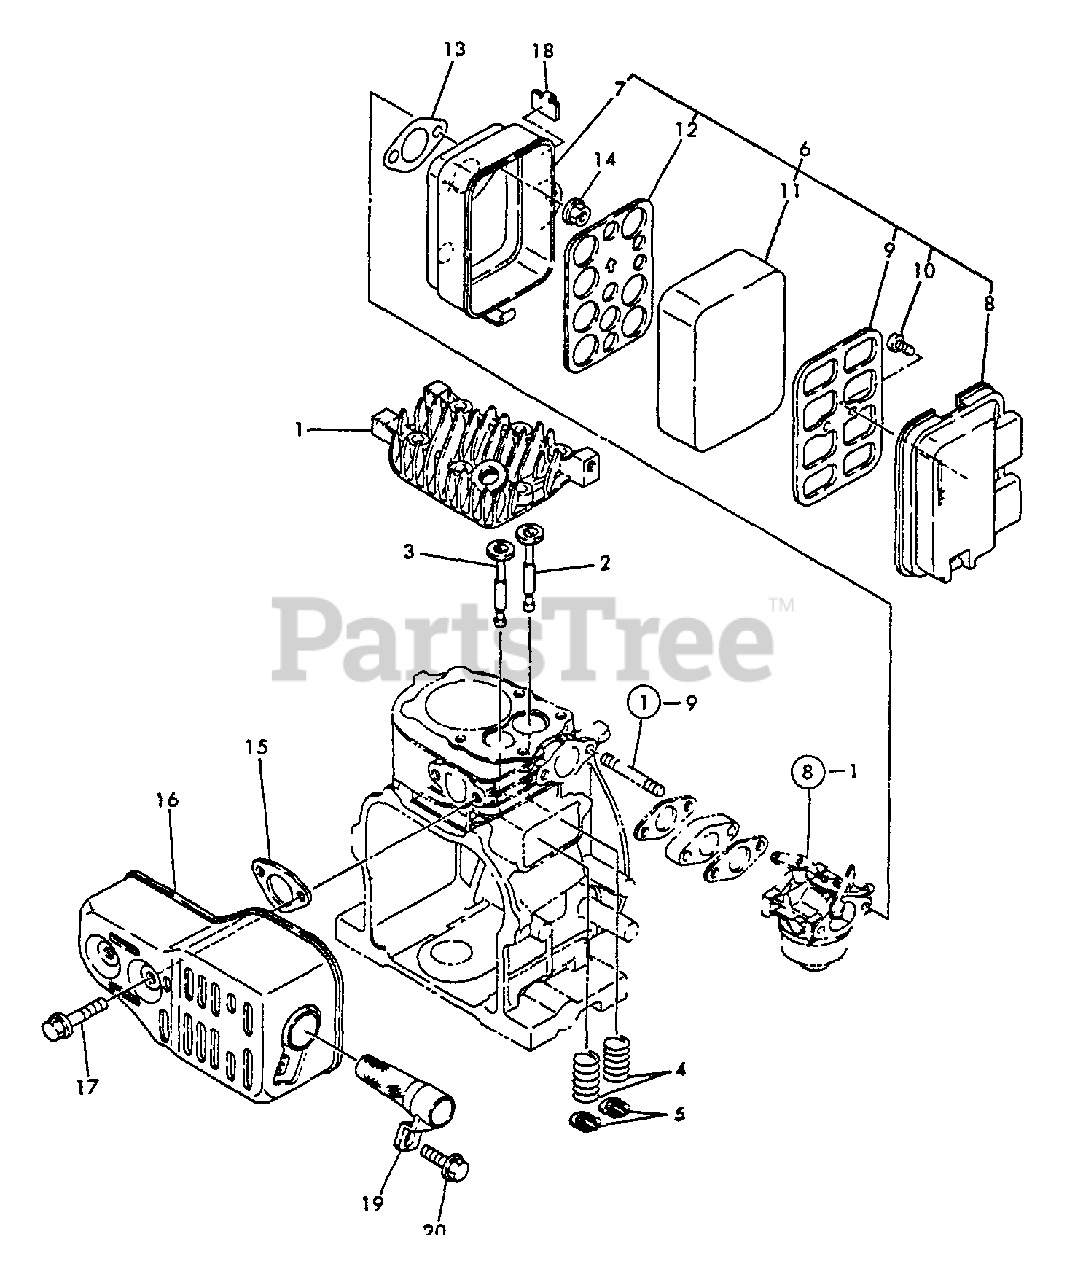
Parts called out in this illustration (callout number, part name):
1	HEAD, CYLINDER
2	VALVE, INTAKE
3	COVER, CRANKCASE
4	SPRING, VALVE
5	RETAINER, VALVE
6	CLEANER ASSY, AIR
7	CASE, AIR FILTER
8	COVER, AIR CLAENER
9	HOLDER (B), ELEMENT
10	SCREW - 5×10
11	FILTER, AIR
12	HOLDER (A), ELEMENT
13	GASKET
14	U-NUT M6
15	GASKET, EXHAUST
16	MUFFLER
17	BOLT - 6×45
18	CLAMP
19	SCREEN, SPARK ARRESTER
20	BOLT - 6×8 -- PLATED
